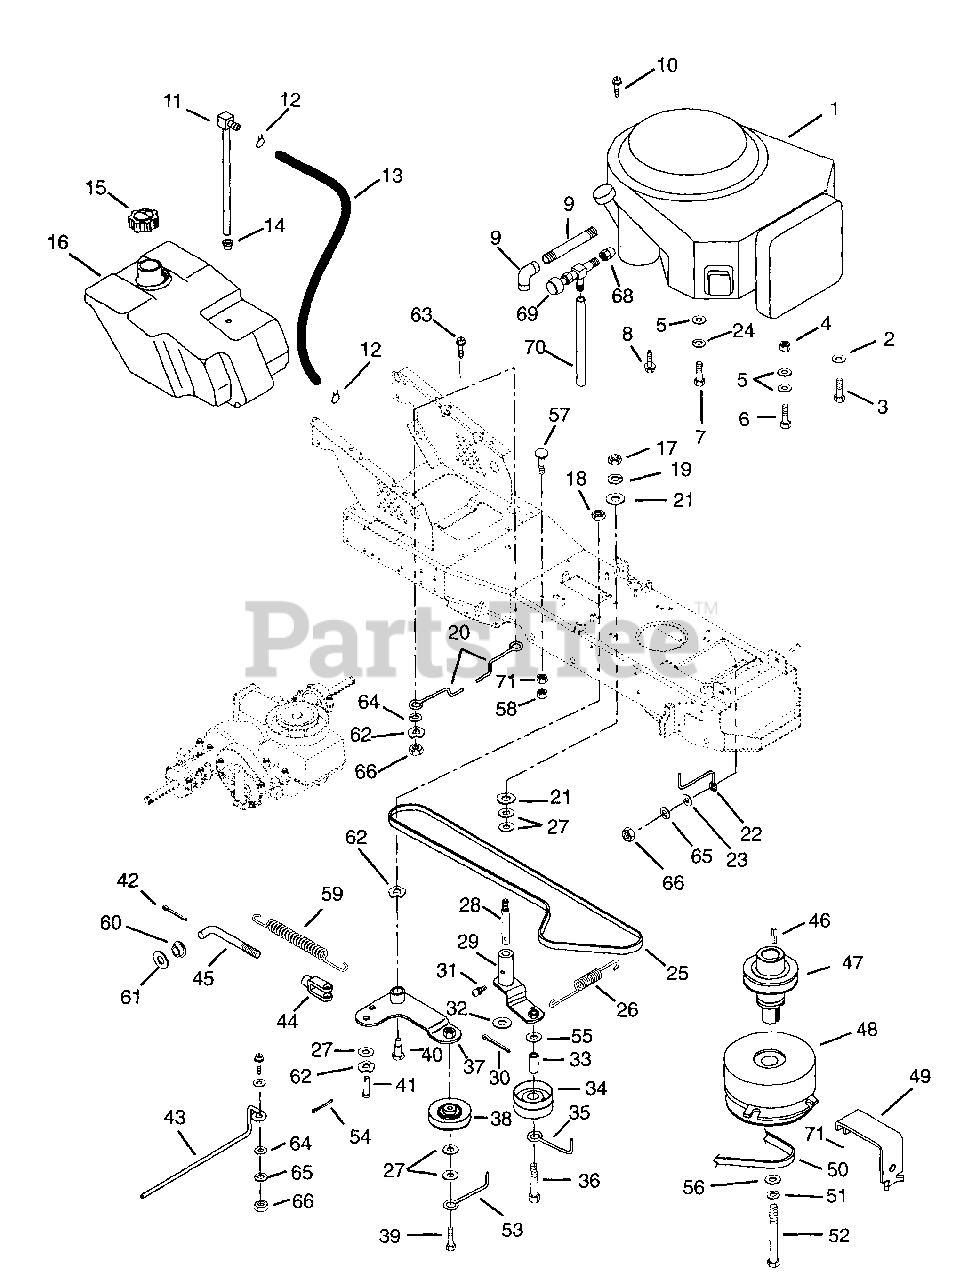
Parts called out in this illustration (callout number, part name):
1	Engine-16.0 B & S Vanguard Twin
1	Engine-15.0 B & S Vanguard Single
1	Engine-15.0 Kohler OHV
2	Washer-Lock External .391 x .682 x .036
3	Screw-Tapping .375-16 x 1.25
4	Nut-Locking-Center .312-18
5	Washer-Flat-Steel .328 x .875 x .062
6	Bolt-Hex .31-18 x 1.50 Grade 5
7	Bolt-Hex Metric 8MM-1.25 x 25MM Grade 8
8	Nipple
9	Elbow .375-18
10	Screw-Tapping .312-18 x .75
11	Tank Fitting
12	Hose Clamp
13	Hose-Fuel Line 36"
13	Hose-Fuel Line 48"
13	Hose-Fuel Line 50"
14	Bushing
15	Fuel Cap
16	Fuel Tank
17	Nut-Hex .375-16
18	Nut-Locking Center .375-16
19	Washer-Lock .375 x .094
20	Belt Finger
21	Washer-Flat-Steel .438 x 1.0 x .083
22	Belt Finger
23	Washer-Flat-Steel .312 x .734 x .065
24	Washer-Lock .313 x .078
26	Spring-External
27	Washer-Flat-Steel .390 x .750 x .125
28	Shoulder Stud
29	Arm-Idler Pivot
30	Pin-Cotter .18 x 1.25
31	Fitting-Lube .25-28 x .256
32	Washer-Flat-Steel .520 x .827 x .062
34	Idler Flat 3.25 x .38
35	Finger-Belt
36	Bolt-Hex .38-16 x 3.50 Grade 5
37	Idler Pivot Arm
38	Idler-V 3 x .38
39	Bolt-Hex .38-16 x 1.75 Grade 5
40	Bolt-Shoulder .38-16 x 1.25
41	Pin-Clevis .312 x .822
42	Pin-Cotter .09 x .75
43	Finger-Belt
44	Yoke .31-24 x 2.250
46	Key-Square .25 x 1.25 x .25
47	Sheave Extension Shaft-Hydro
48	Electric Clutch/Brake
49	Anchor-Clutch
51	Washer-Lock .438 x .133
52	Screw-Cap .44-20 x 4.00 Grade 5
53	Belt Finger
54	Pin-Hair-Internal .08 x .18 x 1.18
55	Washer-Flat-Steel .390 x .875 x .18
56	Washer-Flat-Steel .463 x 1.375 x .250
57	Bolt-Round Head Squar Neck .31-18 x 1.00
58	Nut-Locking-Center .312-18
59	Spring-Tension .105 x .85 x 5.00
60	Bushing-Flange .320 x .620 x .312 Nylon
61	Washer-Flat-Steel .505 x .880 x .072
62	Wave Washer
63	Bolt-Round Head Square Neck .31-18 x .75 Grade 5
64	Washer-Flat-Steel .344 x .688 x .065
65	Washer-Lock .312 x .097
66	Nut-Hex .31-18
67	J-Clamp
68	Adapter-Oil Drain
69	Cock-Oil Drain
70	Tube-Oil Drain
71	Nut-Nylock .312-18
